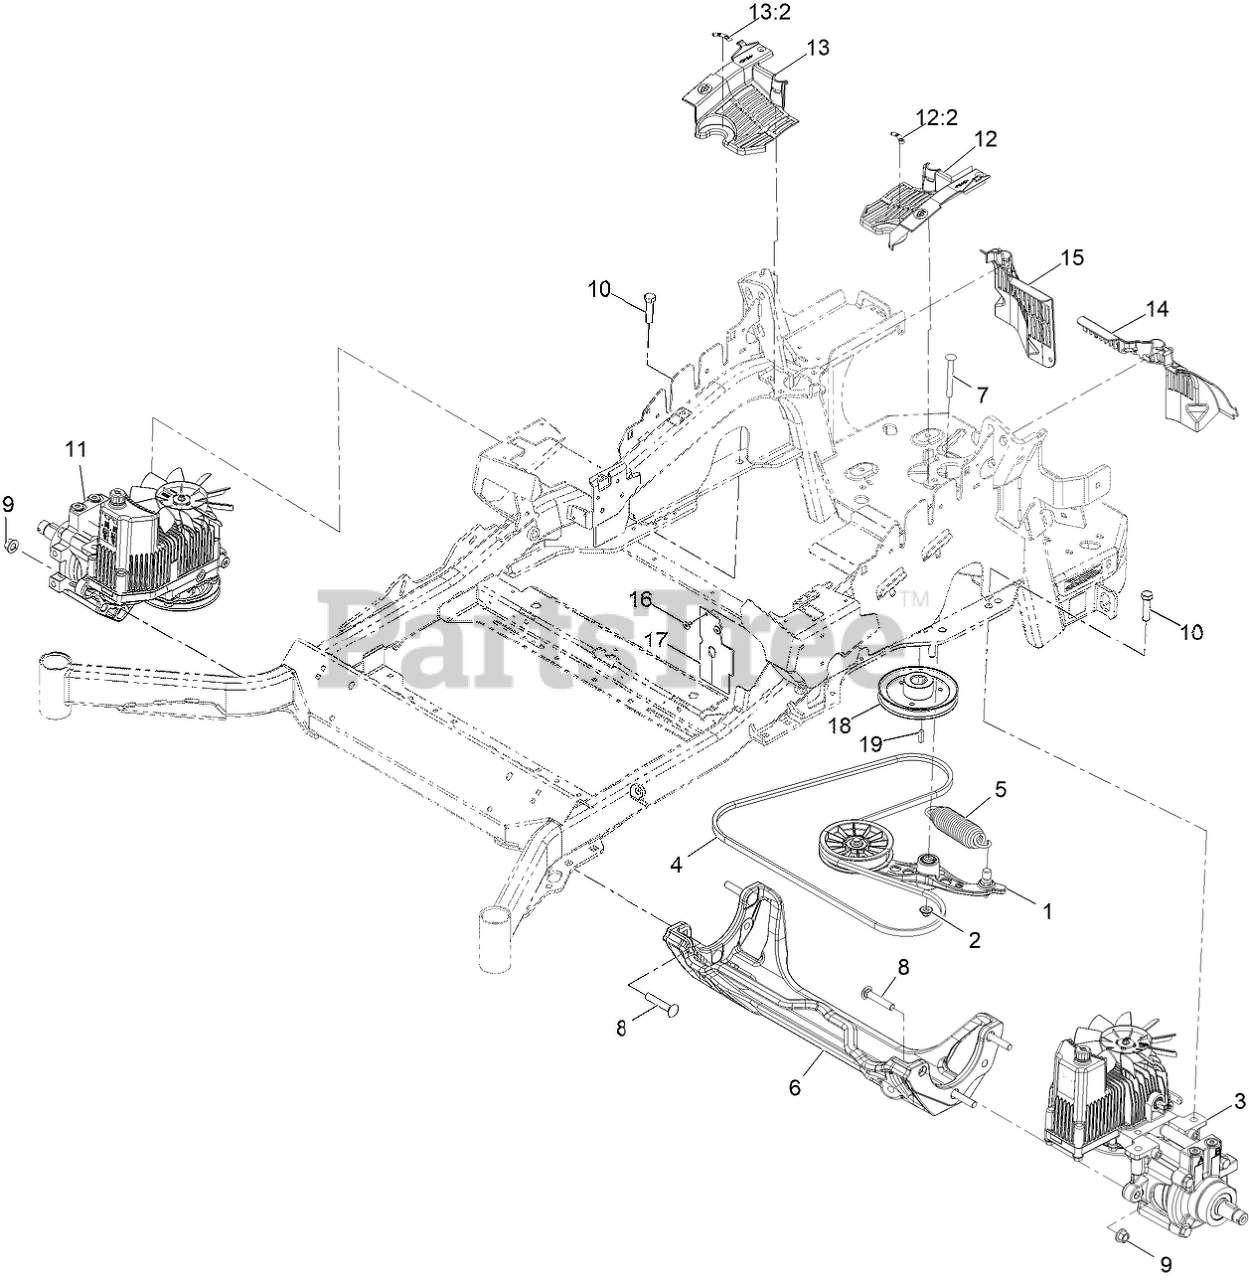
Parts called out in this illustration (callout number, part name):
1	PUMP IDLER ASM
2	Nut-Nyloc 3/8-16 Flg
3	HYDRO-LH
5	SPRING-EXTENSION
6	CRADLE-HYDRO
7	BOLT-SHOULDER, CARRIAGE 3/8-16 X 3 1/2
8	SCREW-CARR
9	Nut-Lock 1/2-13
10	SCREW-HH
11	HYDRO-RH
12	LH HYDRO GUARD ASM
12:2	DECAL-OIL, HYDRO
13	RH HYDRO GUARD ASM
13:2	DECAL-OIL, HYDRO
14	GUARD-HYDRO, REAR LH
15	GUARD-HYDRO, REAR (RH)
16	RIVET-POP
17	DEFLECTOR-AIR FLOW
18	SHEAVE
